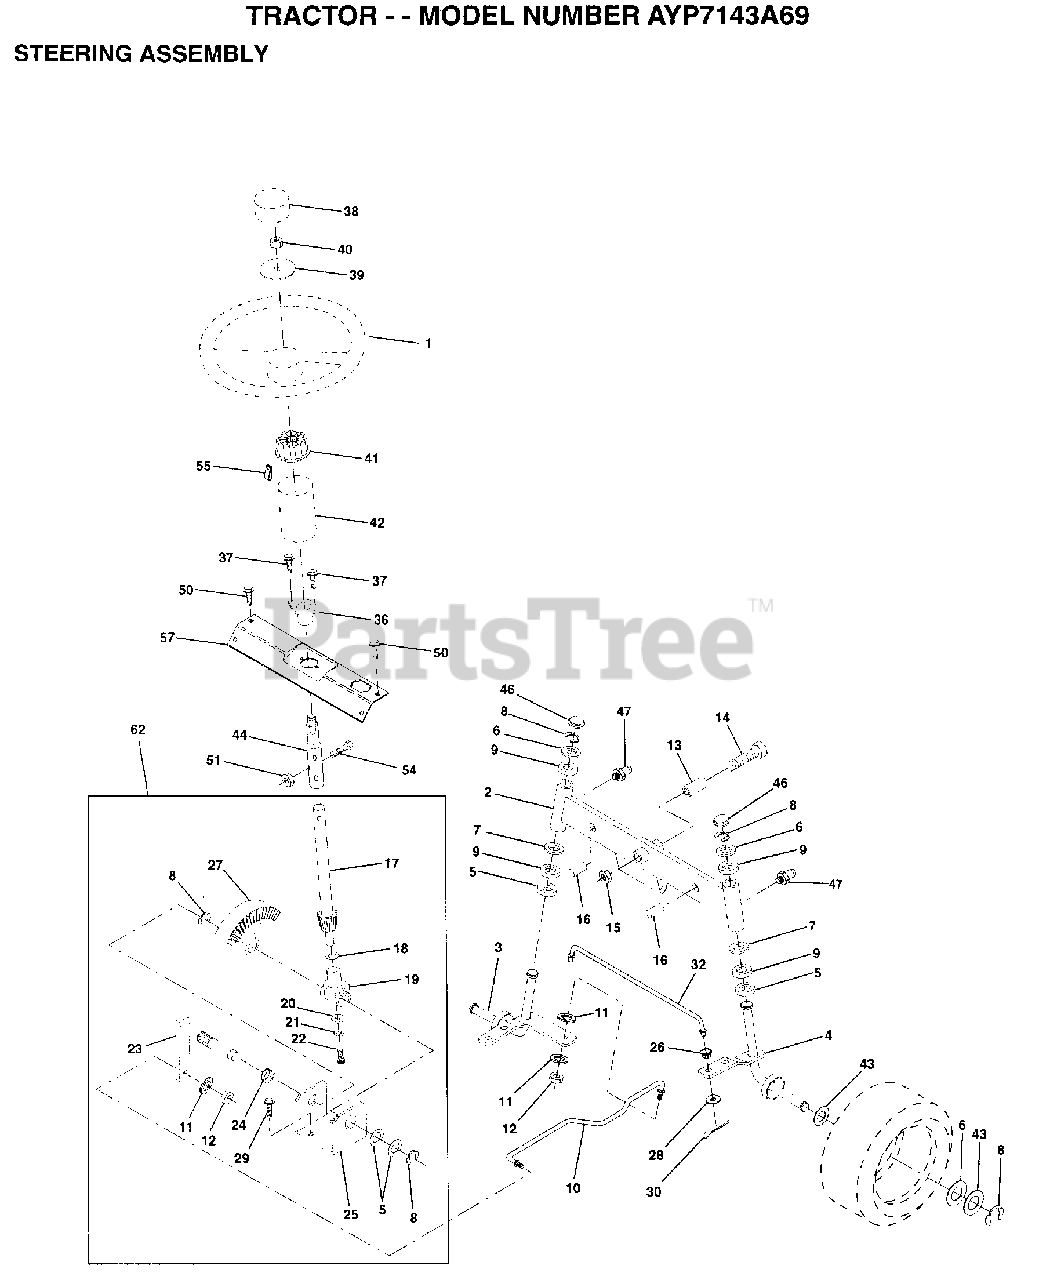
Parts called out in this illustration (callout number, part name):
1	WHEEL STR AYP BLK
2	AXLE ASM FRONT
3	SPINDLE LH
4	SPINDLE RH
5	WASHER .T
6	WASHER
7	WASHER
8	RING
9	COL. SRTG. BEAR.
11	LOCKWASHER
13	BEARING
14	BOLT HEX 5/8-11
15	"NUT-LOC,FLANGE LT"
16	AXLE PIN
17	SHAFT ASM STEERIN
18	THRUST WASHER
19	SUPPORT.SHAFT
21	LOCKWASHER
22	"SCREW,SPECIAL"
24	NYLINER T
25	"BRKT,STEERING"
26	BUSHING.DRAGLINK
27	GEAR SECTOR
28	WASHER
29	SCREW
30	COTTER PIN
32	TIE ROD
38	CAP STEER AYP
39	WASHER T
40	GRIPCO NUT
41	ADAPTER-WHEEL LT
42	BOOT SHAFT STEER
43	WASHER
46	CAP
47	ZERK M
50	SCREW HEX CRT
51	NUT
54	BOLT
55	CLIP TINNERMAN
57	SUPPORT SHAFT STR
